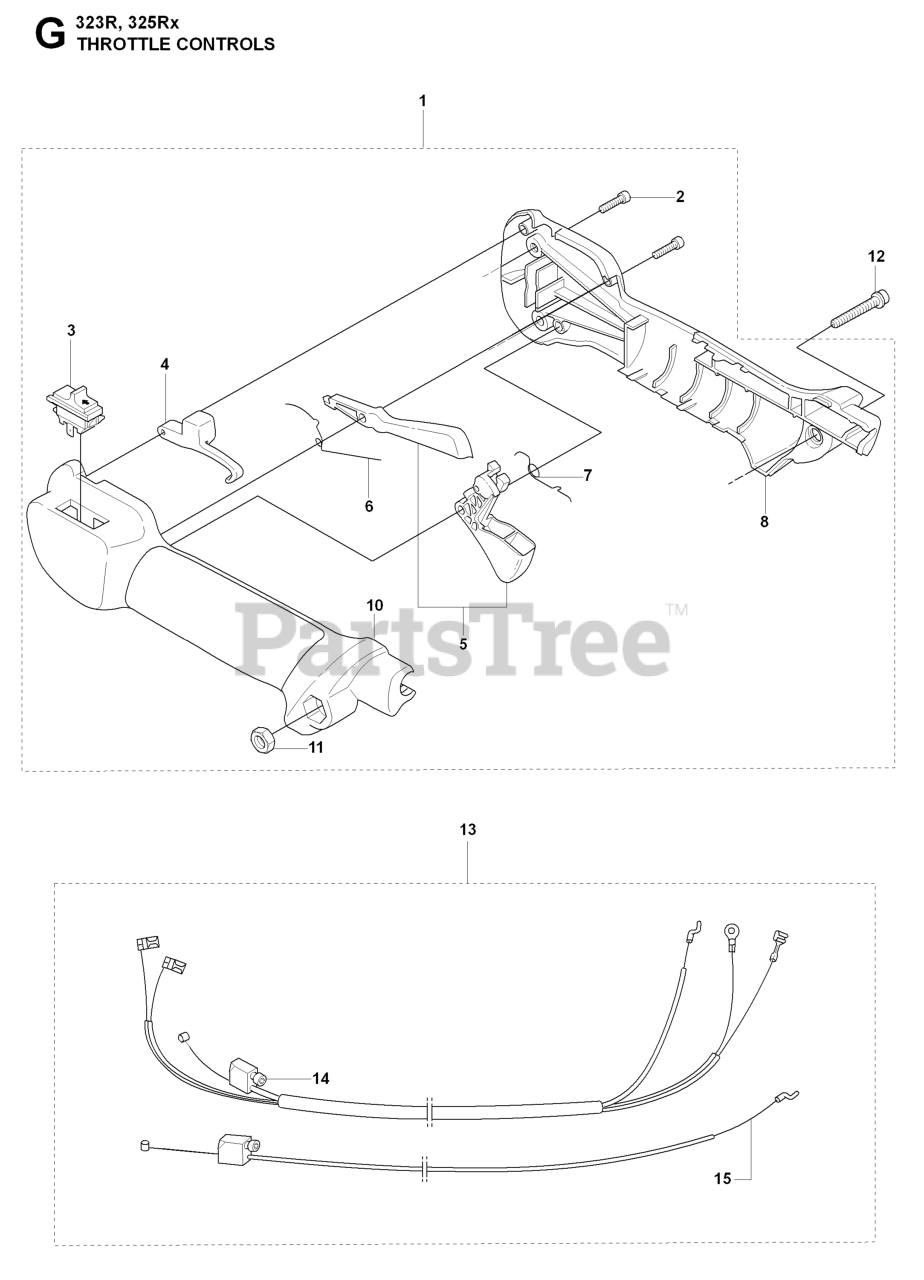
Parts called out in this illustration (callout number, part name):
1	HANDLE SYSTEM ASSY
2	SCREW
3	STOP BUTTON
4	LOCKOUT STARTER THROTTLE
5	THROTTLE CONTROL
10	HANDLE HALF LEFT
12	SCREW
13	CABLE HARNESS COMPLETE
14	SCREW
15	THROTTLE WIRE
